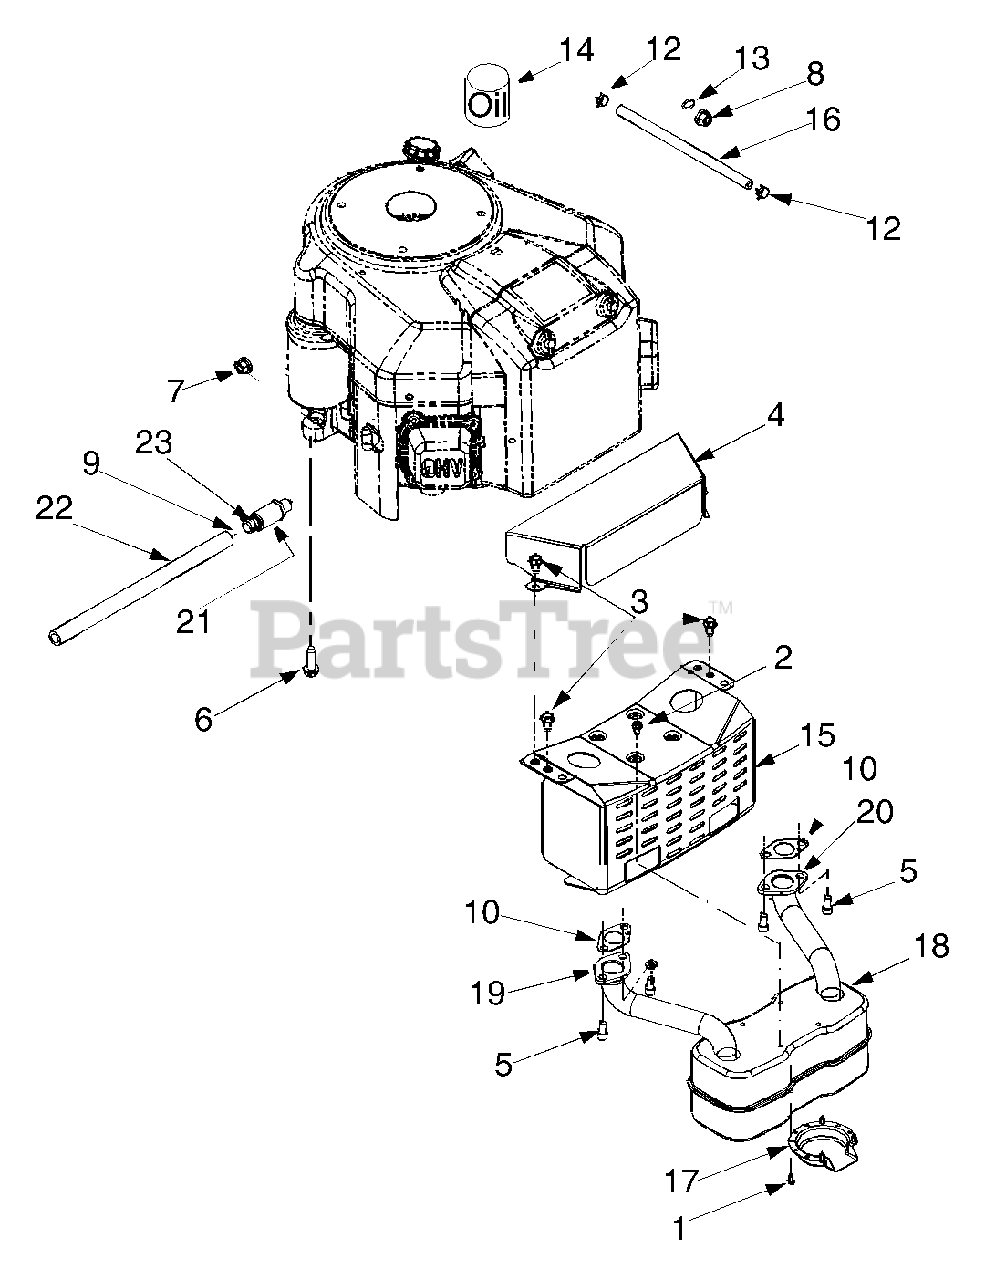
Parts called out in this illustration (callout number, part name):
1	AB Screw 38-18 x 0.5
2	TT Screw 1/4-20 x 0.5
3	AB Screw 5/16-20 x 0.75
5	Socket Hd. Scr. 5/16-18 x 0.75
6	TT Screw 3/8-16 x 1.25
9	Pipe Sealant
10	Exhaust Gasket
14	Oil: SAE 30W
16	Fuel Line Hose
17	Deflector: Muffler
18	Dual Inlet Muffler
19	Exhaust Pipe RH
20	Exhaust Pipe LH
21	Oil Drain
22	Oil Drain Extension Hose
23	Oil Drain Cap
